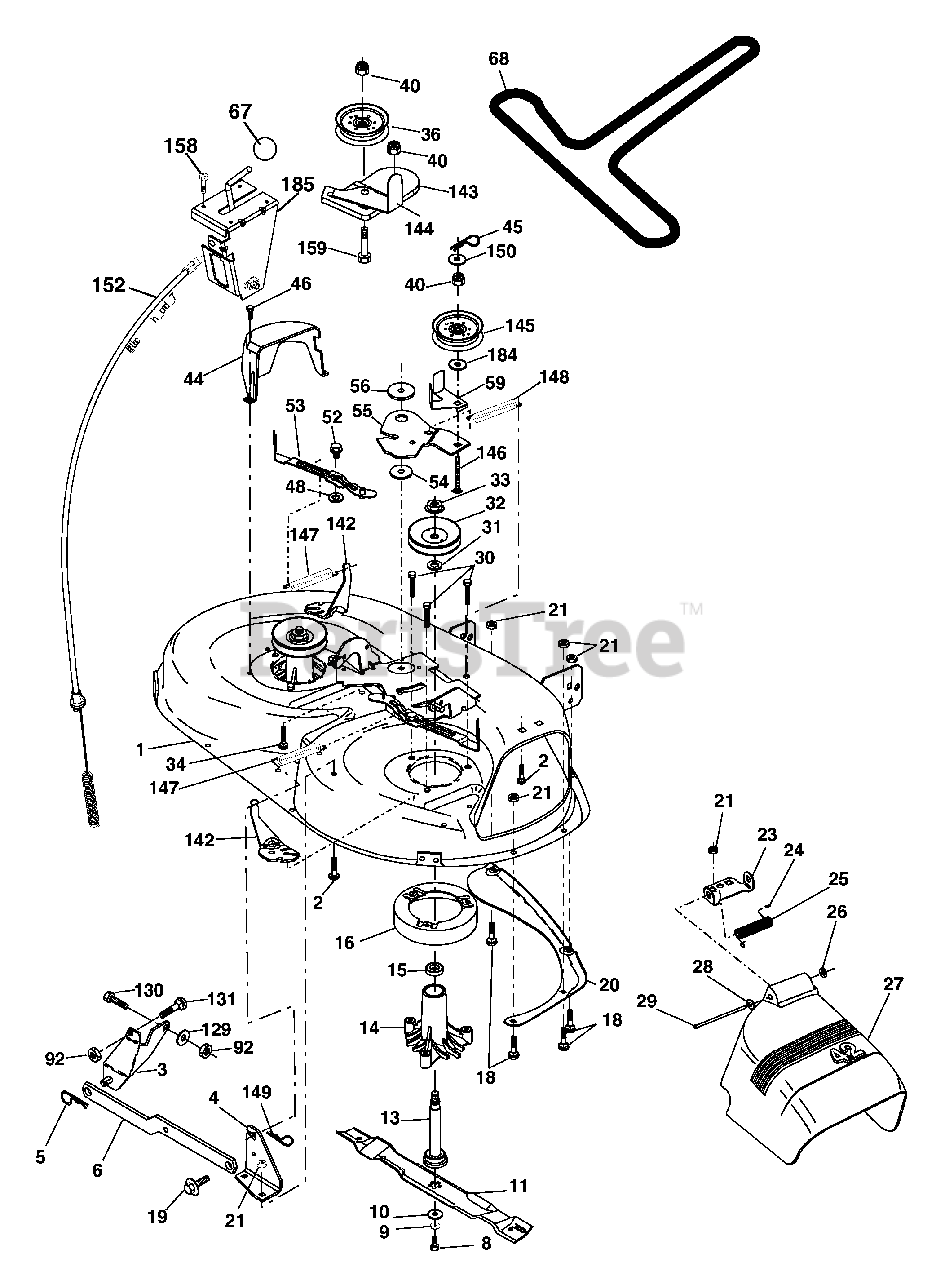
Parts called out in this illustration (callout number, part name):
1	Mower Deck Assembly, 42"
2	Bolt
3	Bracket Asm Fr. Sway Bar 3/42
4	Bracket Asm Deck 42" Sway Bar
5	Retainer Spring
6	Bar Sway Deck
8	Bolt 3/8-24 x 1.25 Gr. 8 patched
9	Washer, Lock
10	Washer, Hardened
11	Blade Mower 42" Hi-Lift
11	Blade, Mulching 42" Std
11	Blade Mulching 42" Premium
13	Shaft Assembly, Mandrel, Vented
14	Housing, Mandrel, Vented
15	Bearing, Ball, Mandrel
16	Stripper, Mandrel Deck
18	Bolt, Carriage 5/16-18 x 5/8
19	Bolt, Shoulder
20	Baffle, Vortex
21	Nut
23	Bracket, Deflector Mower 42"
24	Cap, Sleeve 80 x 112 Blk Mower
25	Spring, Torsion, Deflector 2 52
26	Nut, Push Phos & Oil
27	Shield, Deflector 42" Blk
28	Washer 11/32 x 5/8 x 16 Ga.
29	Rod, Hinge 42" 6 75 W/G
30	Screw Thdrol
31	Washer, Spacer Mower Vented
32	Pulley, Mandrel
33	Nut, Toplock
34	Bolt Carr SH 3/8-16 x 1-1/2 Gr.5
36	Pulley, Idler, Flat
40	Nut Lock 3/8-16
44	Guard, Mandrel, LH
45	Retainer
46	Screw, Thdrol 1/4-20 x 5/8 T
48	Washer, Hardened
52	Bolt, Shoulder 5/16-18 unc
53	Arm Assembly, Pad, Brake
54	Washer, Hardened
55	Arm, Idler
56	Spacer, Retainer
59	Guard TUV Idler
67	Knob Round
68	V-Belt, 42" Mower
92	Nut Lock Hex W/Ins 3/8-16 UNC
129	Washer 13/32 x 13/16 x 12 Ga.
130	Bolt Fin Hex 3/8-16 UNC x Gr. 5
131	Bolt RDHD SQNK 3/8-16 UNC x 1
142	Arm Spring Brake Mower
143	Bracket Arm Idler 42"
144	Keeper Belt 42" Clutch Cable
145	Pulley Idler Flat
146	Bolt Carriage Idler
147	Spring Extension
148	Spring Return Idler
149	Retainer Spring Yellow
150	Washer 9/32 x 3/4 x 10 Ga.
152	Clutch Cable 42"
158	Screw Hex Thd Cut 1/4-20 x 1/2
159	Bolt Rdhd Sqn 3/8-16 unc x 1-3/4
184	Washer 13/32 x 7/8 x 10 Ga.
185	Head Asm Cable Clutch
